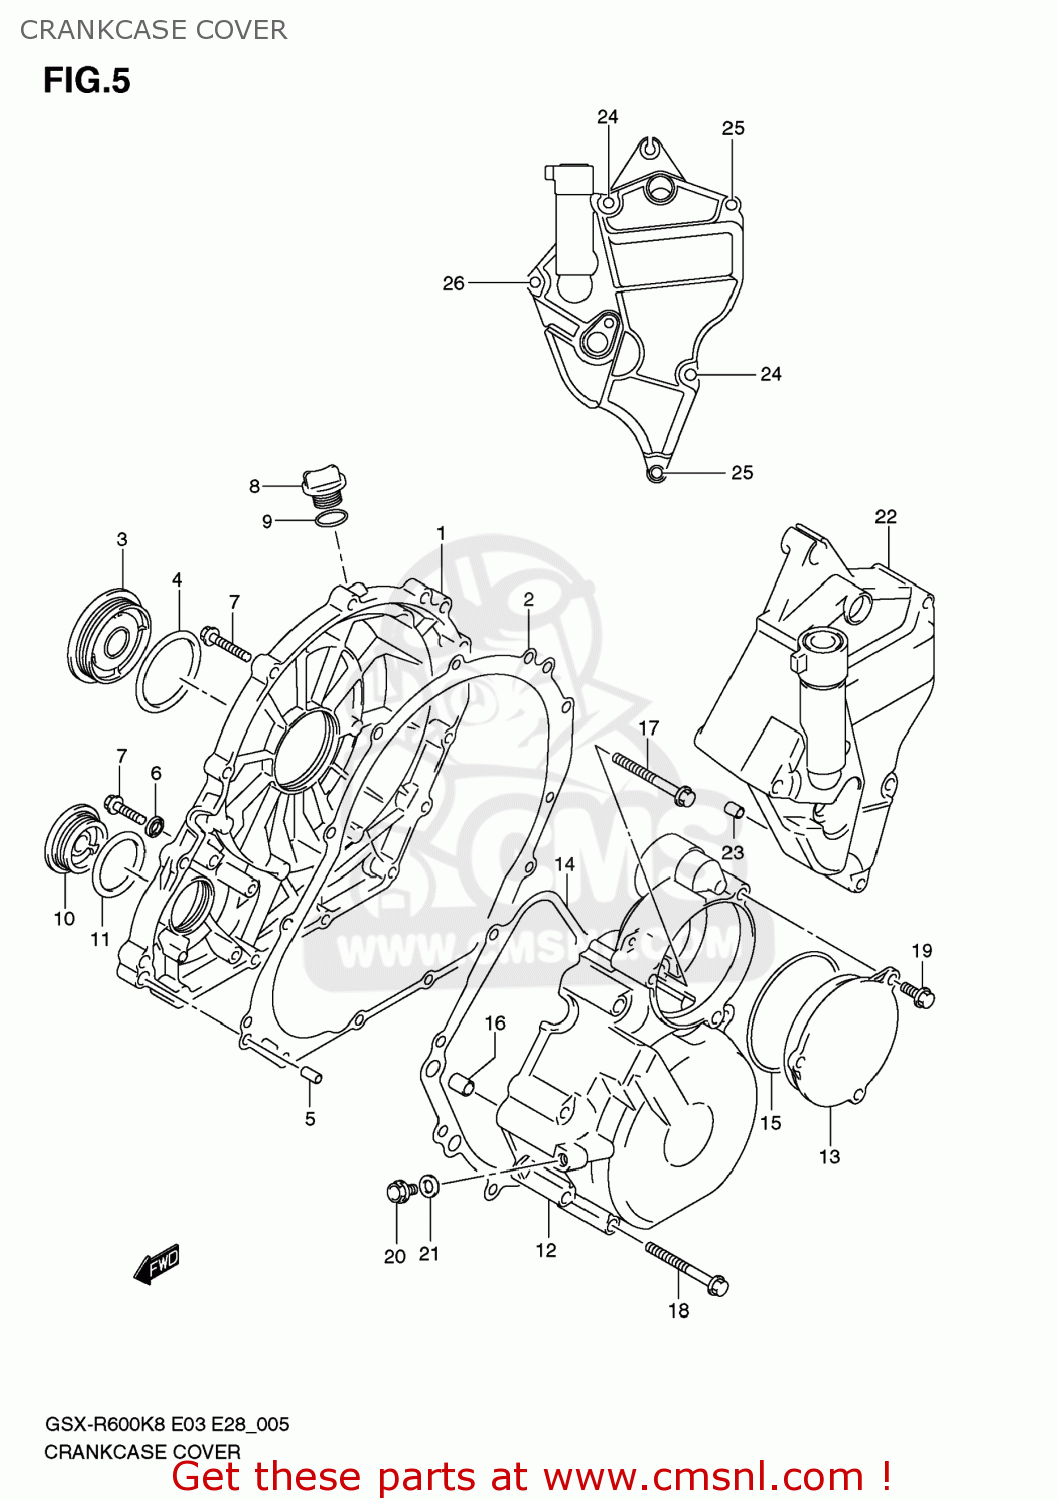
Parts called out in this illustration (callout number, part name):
1	COVER,CLUTCH
2	GASKET,CLUTCH COVER (NAS)
3	CAP,CLUTCH RELEASE ADJUST
4	O RING(D:2.4,ID:52.6)
5	PIN
6	GASKET(5.8X13X1.2) (NAS)
7	BOLT(6X30)
8	PLUG,ENGINE OIL FILLER
9	O RING(D:3.1,ID:16.8)
10	PLUG
11	O RING(D:3.1,ID:32.7)
12	COVER,GENERATOR
13	CAP,STARTER IDLE GEAR
14	GASKET,GENERATOR COVER (NAS)
15	O RING(D:2.6,ID:67.1)
16	PIN
17	BOLT(6X25)
18	BOLT(6X50)
19	BOLT(6X16)
20	BOLT(6X12)
21	GASKET(6.2X13X1.2) (NAS)
22	COVER,ENGINE SPROCKET
23	PIN
24	BOLT(6X45)
25	BOLT(6X65)
26	BOLT(6X75)
